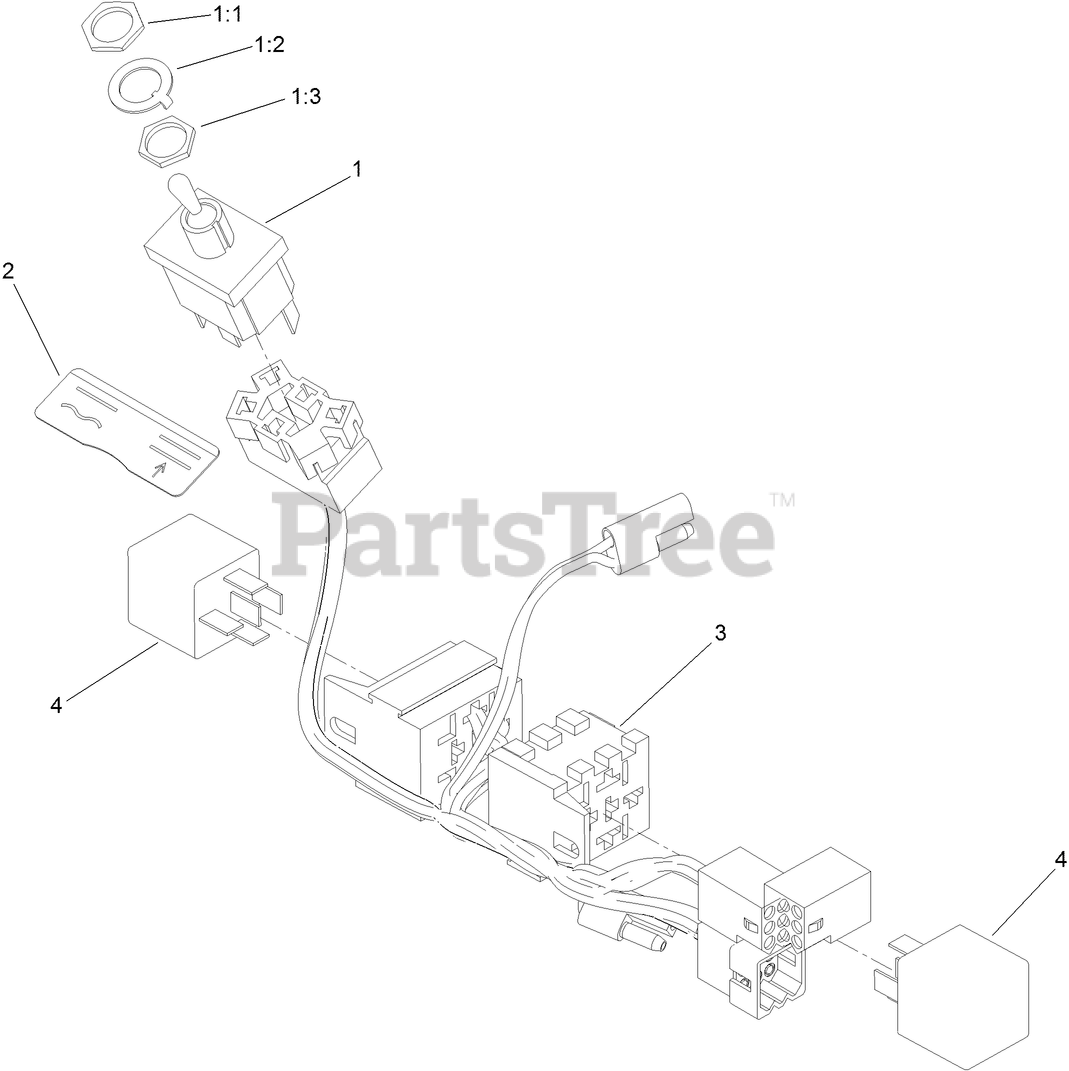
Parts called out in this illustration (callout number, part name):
1	SWITCH-TOGGLE, SEALED
1:1	NUT-HEX, SPECIAL
1:2	TAB-WASHER
1:3	NUT-LOCK
2	DECAL-ATTACHMENT, FLOAT
3	HARNESS-WIRE, FLOAT KIT
